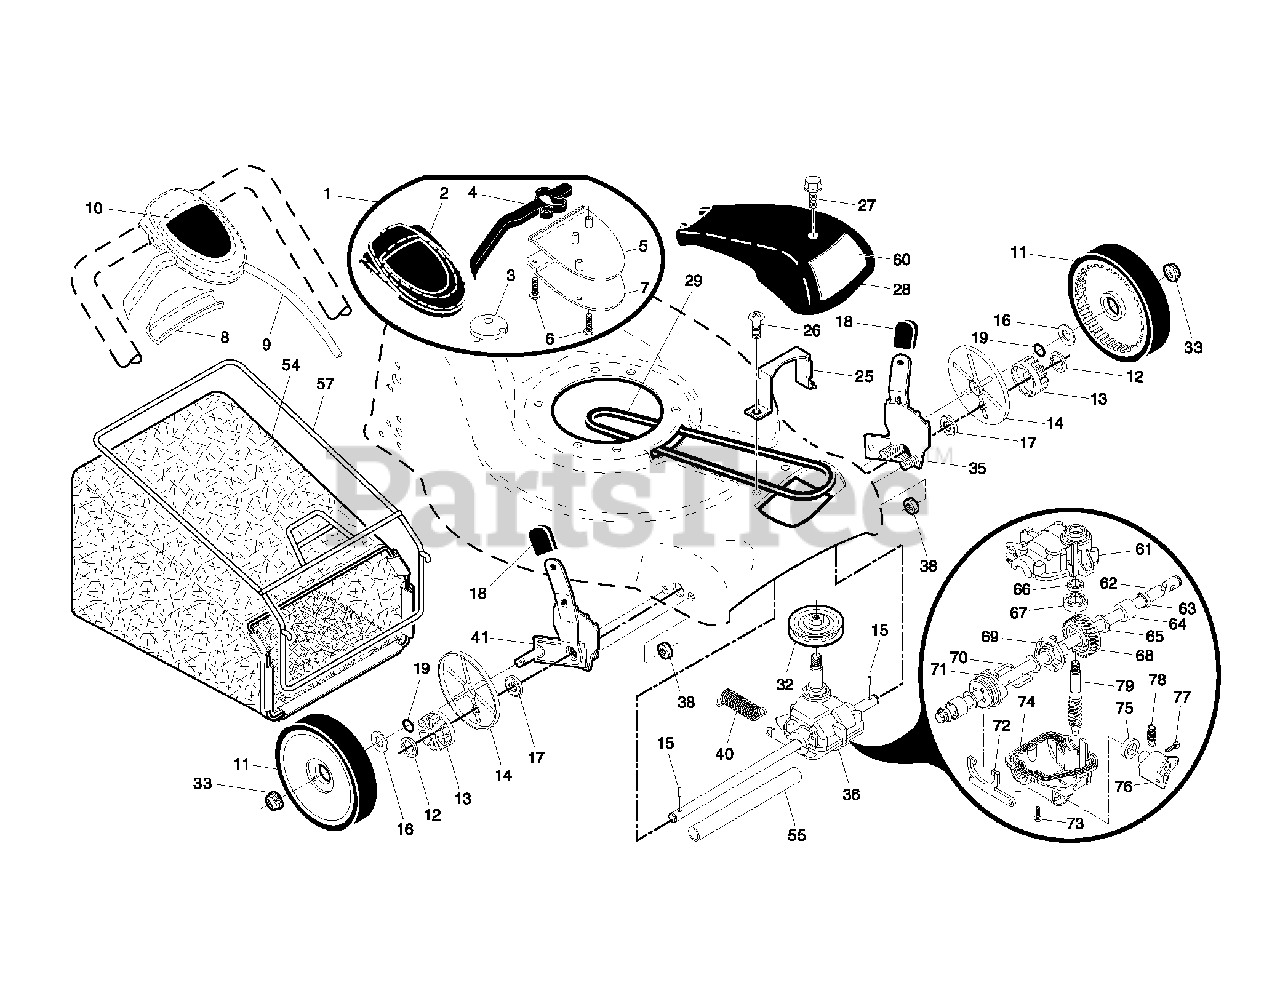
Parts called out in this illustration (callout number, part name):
3	PULLEY, DRIVE CONTROL
6	SCREW, PHILLIPS HEAD 10 X 5/8
7	BRACKET.DRIVE.CONTROL.MOUNT
8	EA WLK COVER PLATE.BLK
9	CABLE.ASM.
12	E-RING 7/16 RE
13	PINION.14.TEETH.FGD
14	COVER.DUST.WHEEL
15	PAWL.DRIVE
16	WASHER FLUT
17	BEARING
18	SELECTOR KNOB
25	KEEPER.BELT.21.EZ.FWGD
26	SELF-TAPPING SCREW 5/16-18X3/4
27	SCREW, HEX HD TAPPING #10-24 1
29	BELT.DRIVE.FGD.
32	RP PULLEY.DRIVE.EZ
33	HEX FLANGE LOCKNT
35	RP KIT.ADJUSTER.ASM.
36	TRANSMISSION.21RD
38	LOCKNUT
40	SPRING RETURN
54	GBAG.34710010.BLACK.GE
55	DRIVESHAFT COVER
57	FRAME, GRASSBAG
61	GEARCASE.HOUSING
62	SHAFT.OUTPUT
63	SEAL.OUTPUT.SHAFT
66	SEAL INPUT SHAFT
68	GEAR.27.TEETH.WALK.MOWER
70	WIRE, FORMED
74	GEARCASE.HOUSING
77	SCREW.LEVER.
79	SHAFT, INPUT
